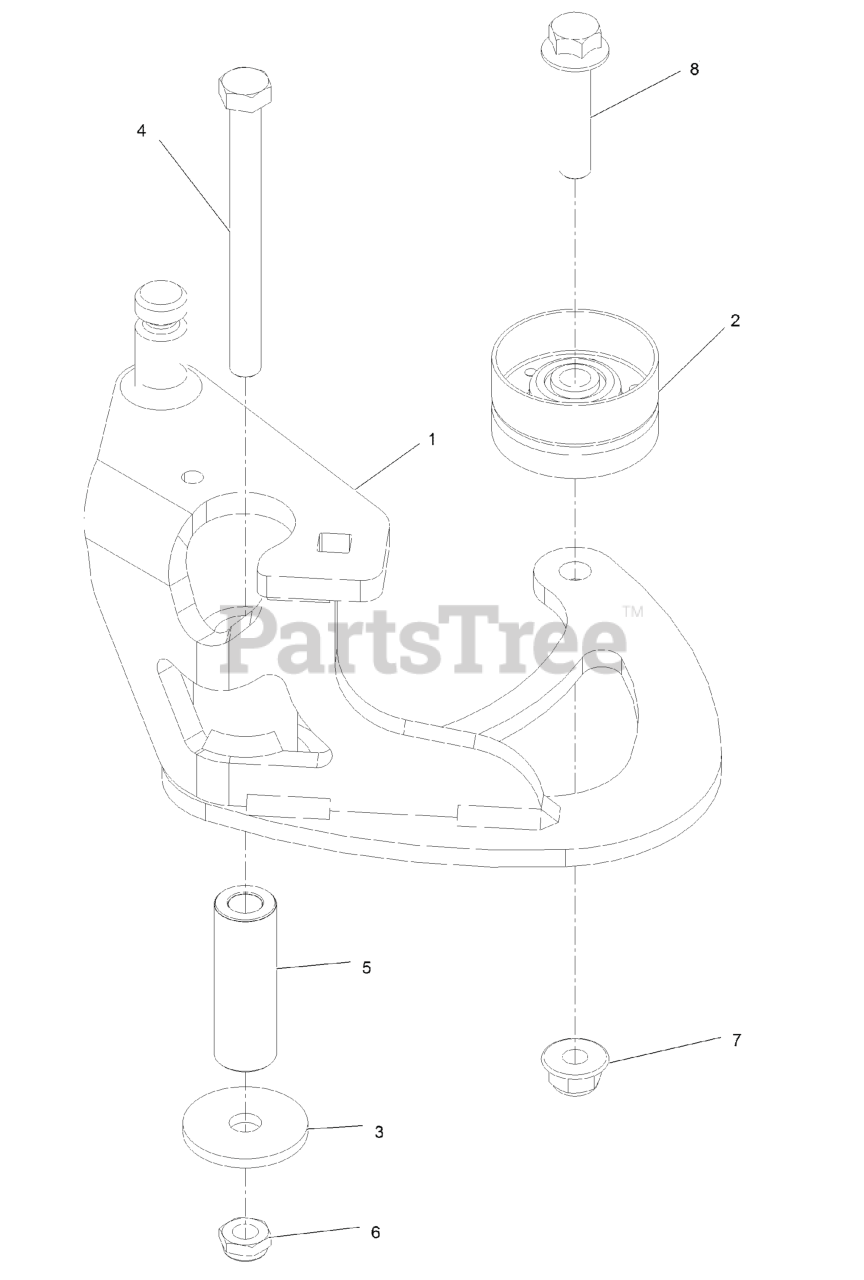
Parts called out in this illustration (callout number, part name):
1	ASM, IDLER ARM W/ BUSHINGS
2	IDLER, FLAT
4	SCREW-HH
5	TUBE, IDLER PIVOT
7	NUT-HF, NI
8	SCREW-HHF
